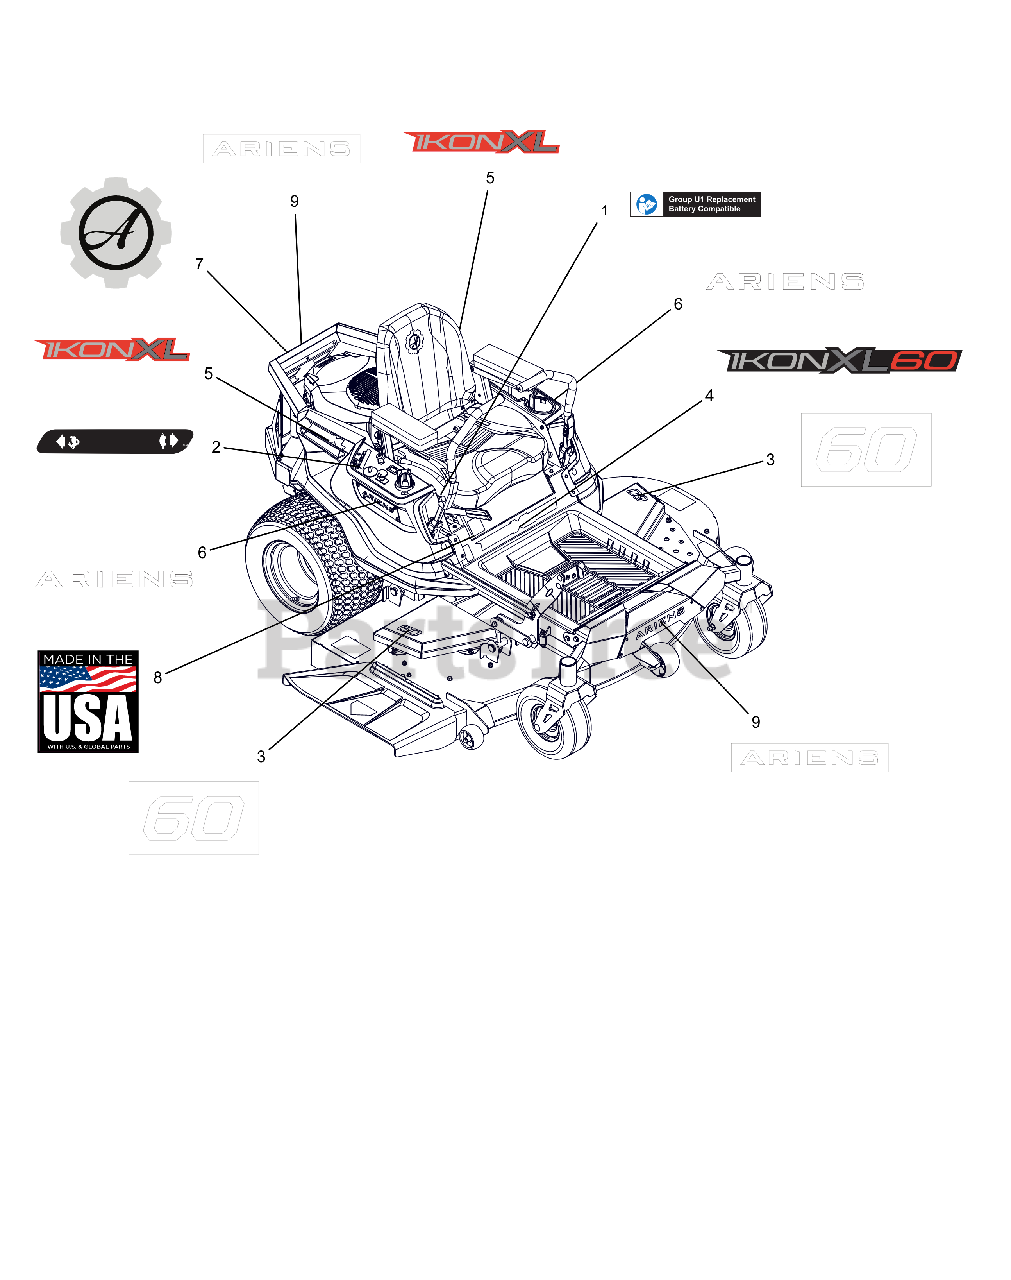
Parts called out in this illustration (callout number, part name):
1	DECAL, U1 BATTERY REPLACEMENT
2	DECAL, DASH DECAL
3	DECAL, 60"
4	DECAL, IKON-XL 60"
5	DECAL, IKON-XL
6	DECAL, ARIENS (6.50")
7	DECAL, ARIENS-GEAR BADGE
8	DECAL, MADE IN USA
9	DECAL - ARIENS 9.625"
